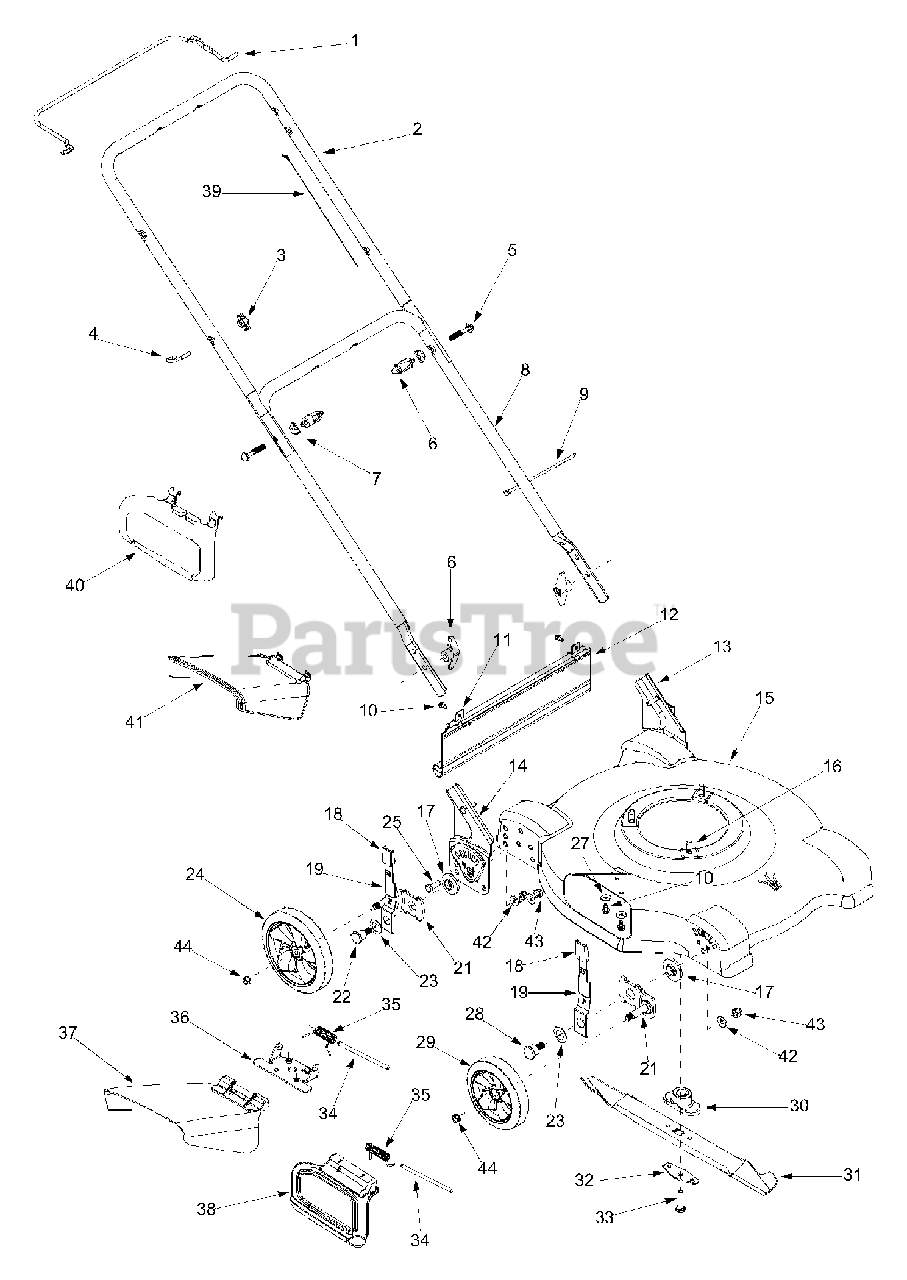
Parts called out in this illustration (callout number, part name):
3	Wing Nut
4	Eye Bolt
5	Carriage Bolt 5/16-18 x 2.0
6	Wing Nut
7	Shoulder Washer .320 ID x .93 OD
9	Cable Tie
10	Hex Screw 1/4-14 x .625
11	Hinge Clip
12	Trail Shield
16	Hex Washer Screw 3/8-16 x 1.0
17	Height Adjuster Bearing
18	Height Adjuster Knob
19	Spring Lever
20	Hex Cap Screw 3/8-16 x .75
21	Pivot Arm
22	Shoulder Screw
23	Bell Washer .760 ID x 1.25 OD
24	Rear Wheel 8 x 1.8
25	Hex Cap Screw 3/8-16 x 1.0
26	Flange Lock Nut 3/8-16
27	Bell Washer .265 ID x .75 OD
28	Shoulder Screw
29	Front Wheel 7 x 1.8
30	Blade Adapter
31	Blade 22"
32	Blade Bell Support
33	Hex Cap Screw 3/8-24 x 1.5
34	Hinge Pin
35	Torsion Spring
36	Chute Hinge
37	Side Discharge Chute Assembly
38	Mulching Baffle
39	Blade Control Cable - B&S (37.25)
40	Snap Mulching Plug
41	Snap Discharge Chute
42	Washer Spacer .401 ID x .870 OD
43	Hex Lock Nut 3/8-16
44	Lock Nut 3/8-16
